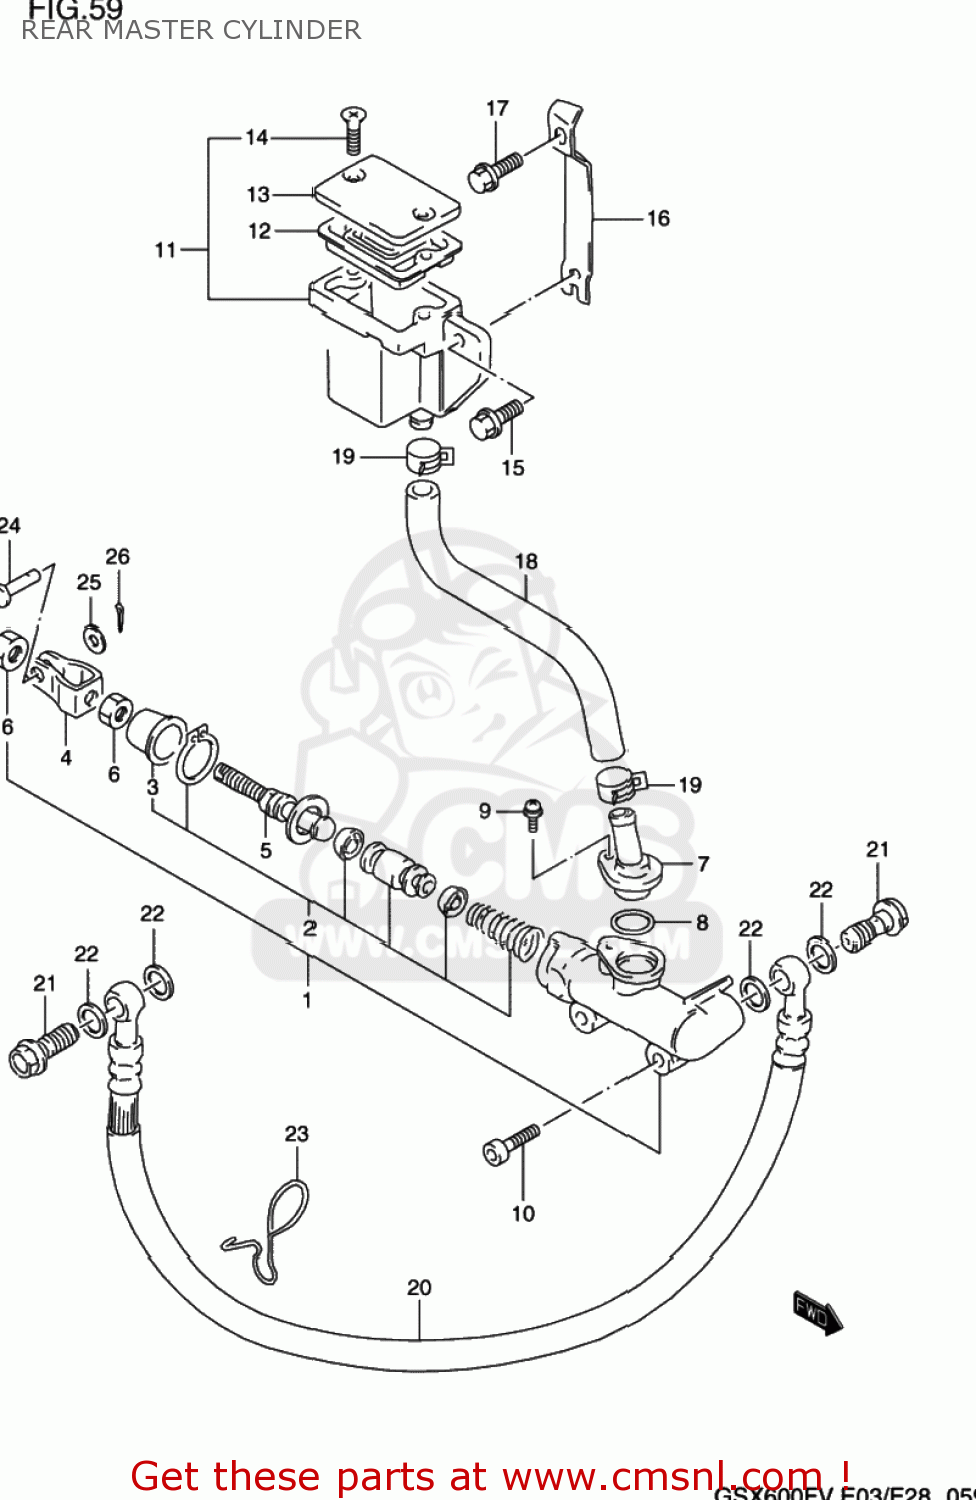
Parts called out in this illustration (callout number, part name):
1	CYLINDER ASSEMBLY,REAR MASTER
2	PISTON/CUP SET
3	BOOT
4	YOKE
5	ROD,PUSH
6	NUT
7	CONNECTOR
8	O RING
9	SCREW
10	BOLT,OIL FILLE
11	TANK ASSY,RESERVOIR
12	DIAPHRAGM
13	CAP
14	SCREW
15	BOLT
16	PLATE,RESERVOIR TANK
17	BOLT
18	HOSE,RESERVOIR TANK
19	CLIP
20	HOSE,RR BRAKE
21	BOLT UNION
22	WASHER(10X15X1.5)
23	GUIDE,BRAKE HOSE
24	PIN
25	WASHER
26	PIN
